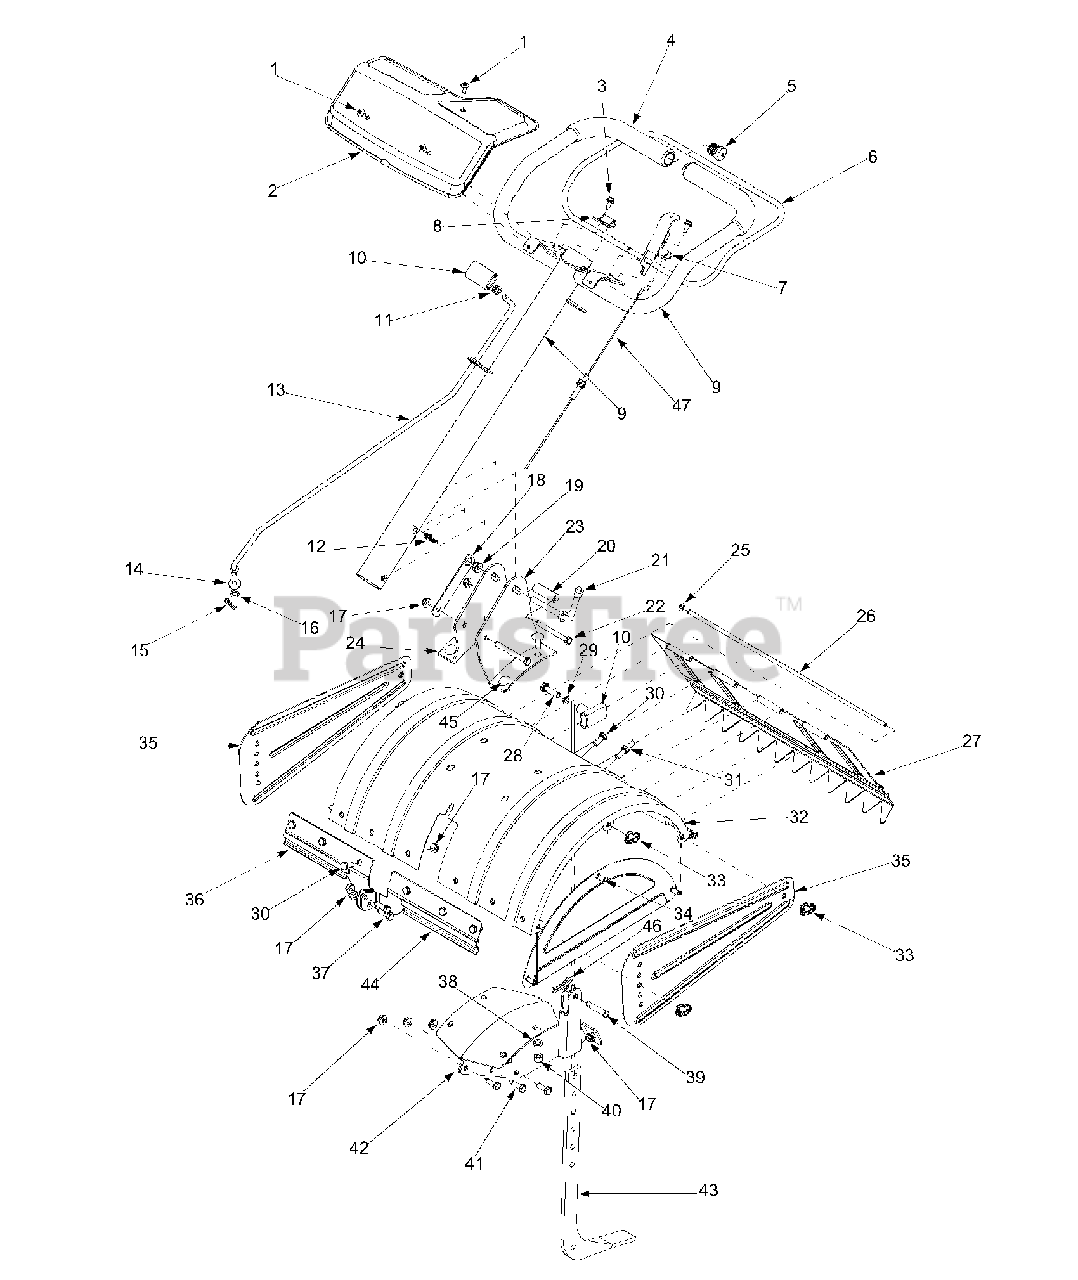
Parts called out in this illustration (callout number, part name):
1	Tap Screw 1/4-14 x .625
4	Foam Grip
5	End Plug
11	Jam Nut 3/8-16
12	Cable Clip
13	Shift Control
14	Rubber Washer .33 ID x .87 OD
15	Cotter Pin
16	Flat Washer .344 ID x .62 OD
17	Hex Flange Lock Nut 5/16-18
18	Retainer Bracket
19	Flange Lock Nut 3/8-24
20	Spacer .322 ID x .625 OD
21	Adjustable Crank Handle
22	Hex Screw 5/16-18 x 3.0
28	Hex Cap Screw 3/8-16 x 1.25
29	Flat Washer .375 ID x .620 OD
30	Hex Cap Screw 5/16-18 x .75
31	Hex Screw 5/16-18 x .75
37	Hex Cap Screw 5/16-18 x 1.0
38	Lock Washer 3/8
39	Clevis Pin
40	Hex Nut 3/8-16
41	Hex Cap Screw 5/16-18 x .875
45	Carriage Bolt 3/8-16 x 1.0
46	Cotter Pin
47	Clutch Cable
